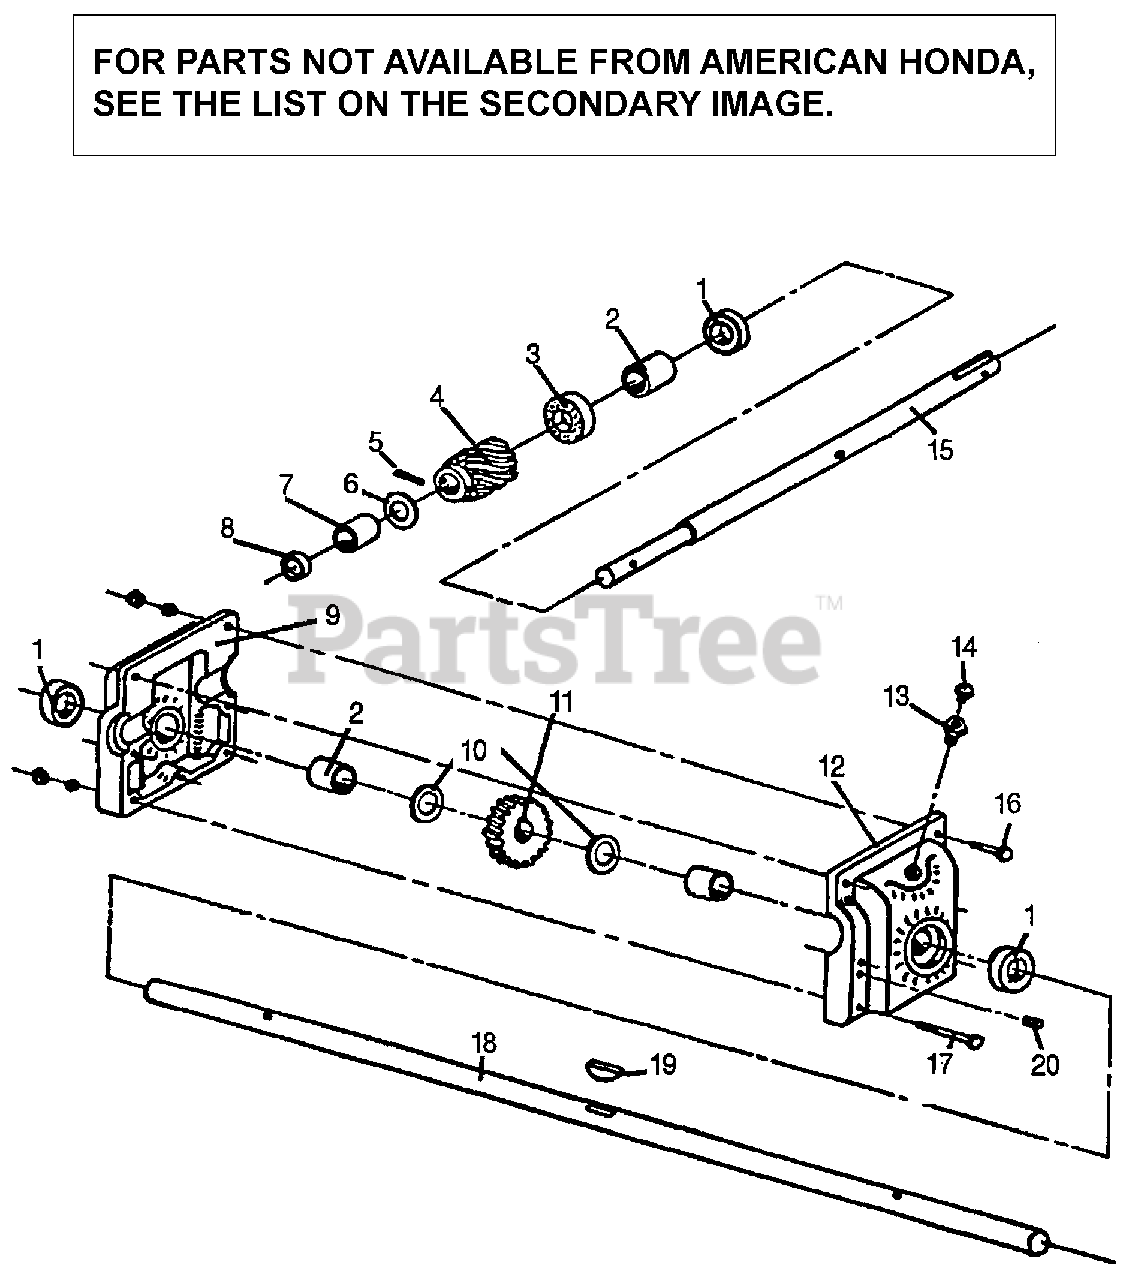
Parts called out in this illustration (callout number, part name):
1	OIL SEAL (GR 9818)
2	BUSHING (1X1-1/4")
3	BEARING (SKF 51105)
4	WORM, RH ROTATION
5	PIN (1/4X1-1/2")
6	WASHER (1-3/8")
7	BUSHING (7/8X1-1/8")
8	CAP, INPUT
9	COVER, R.
10	WASHER (1-1/2")
11	GEAR, BRASS CLOCKWISE (#65)
12	COVER, L.
13	COUPLING (3/8X1/8")
14	BREATHER (1/8" NPT)
15	SHAFT, INPUT
19	KEY, WOODRUFF
20	PLUG, LEVEL NPT (1/8")
